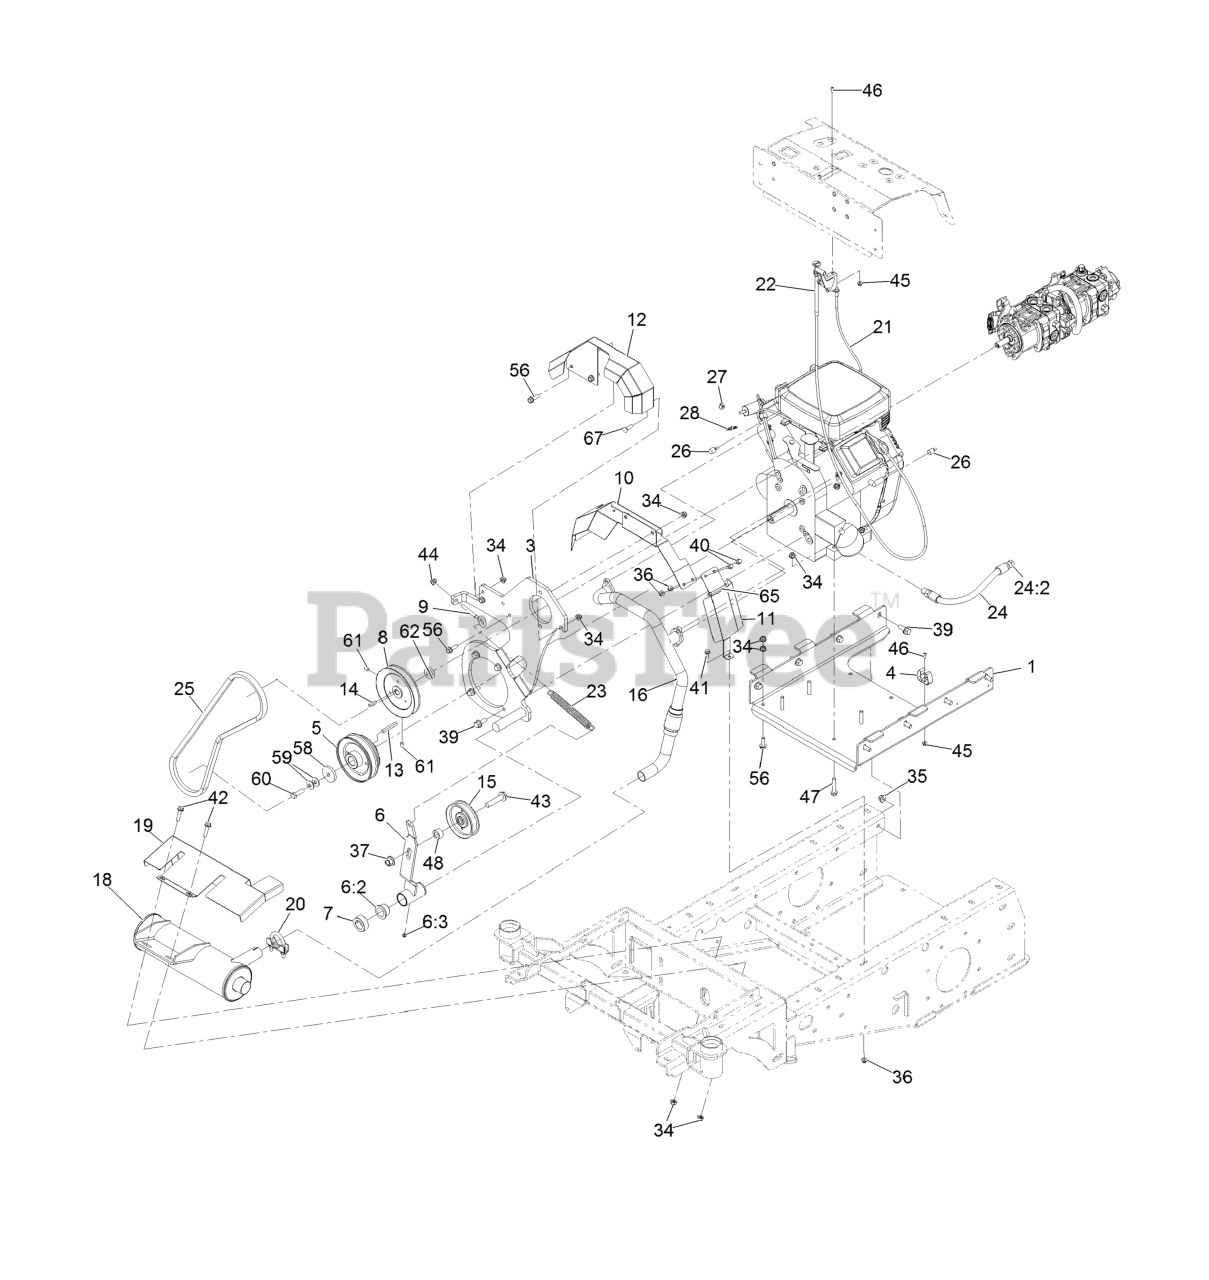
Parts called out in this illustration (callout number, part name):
1	Tray-Engine
3	Bracket-Engine, Pump [black]
4	Holder-Tool, Clip
5	Pulley-Double
6	Arm-Tension, ASM
6:2	BUSHING-FLANGE
6:3	FITTING-GREASE, ZERK
8	PULLEY-DRIVE, PUMP
9	Bolt-Eye
10	Guard, Lower Muffler
11	Guard, Lower Muffler
12	GUARD-PULLEY
15	PULLEY-IDLER, FLAT
16	MANIFOLD-EXHAUST
18	MUFFLER
19	SHIELD-HEAT, MUFFLER
20	Clamp-Muffler
21	CABLE-THROTTLE
22	CABLE-CHOKE
23	SPRING-EXTENSION
24	ASM, Oil Drain Hose W/Plug
26	Tube-Heat Shrink, 1/2
27	CLAMP-HOSE
28	Fitting-STR
34	Nut-Hex Flange
35	Nut-Hex Flange
36	Nut-Hex Flange
37	Nut-Lock 1/2-13
39	SCREW-HHF
40	SCREW-HHF
41	Screw-HHF
42	SCREW-HHF
43	Screw-HHF
44	NUT-HF, NI
45	Nut-Hex Flange
46	Screw-HSBH
47	Screw-HHF
56	SCREW-HHF
58	WASHER-PLAIN
59	WASHER-BELLEVILLE
60	Screw-HH
61	Setscrew-HSH
65	TIE-CABLE
67	Bolt,Carriage,5/16-18X1,ST/ST 18-8
